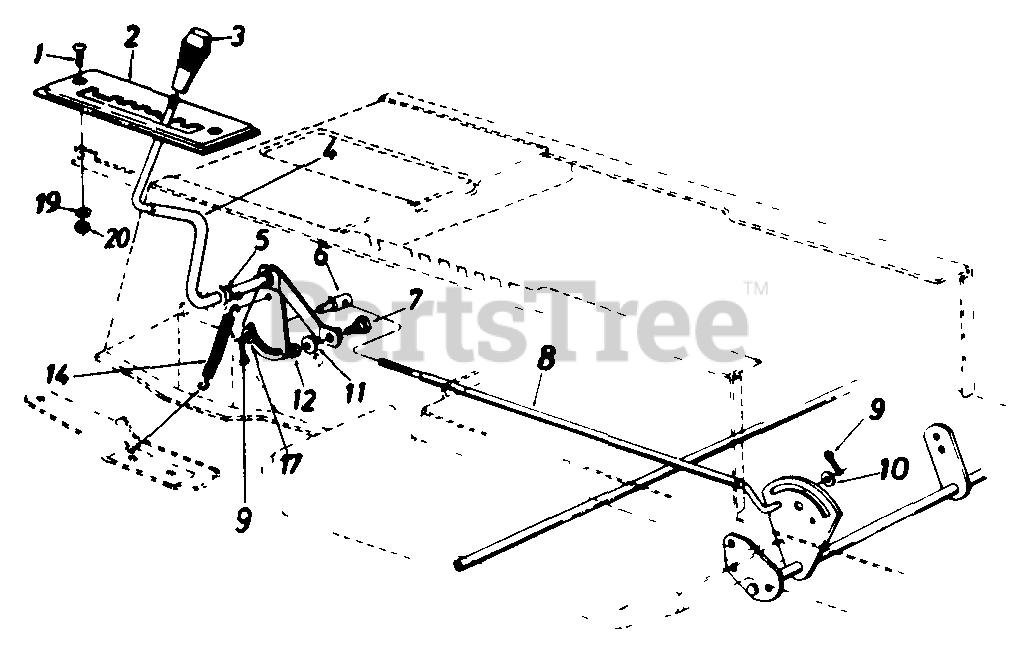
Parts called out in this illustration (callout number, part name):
1	Truss Mach. Scr. 1/4-20 x .75" Lg.
4	Speed Selector Lever Ass'y.
5	Flat Washer .53" I.D. x .93"
6	Ferrule 3/8-24 x .37" Dia.
7	Shoulder Bolt
8	Speed Control Link
9	Cotter Pin 3/32" Dia. x 1.0"
10	Fl-Wash. .469" I.D. x .88"
11	L-Wash. 5/16" I.D.
12	Hex Nut 5/16-18 Thd.
14	Spring .38" O.D. x 3.18" Lg.
17	Fl-Wash. .385" I.D. x .62"
19	Fl-Wash. 1/4" I.D.
20	Hex Nut 1/4-20 Thd.
